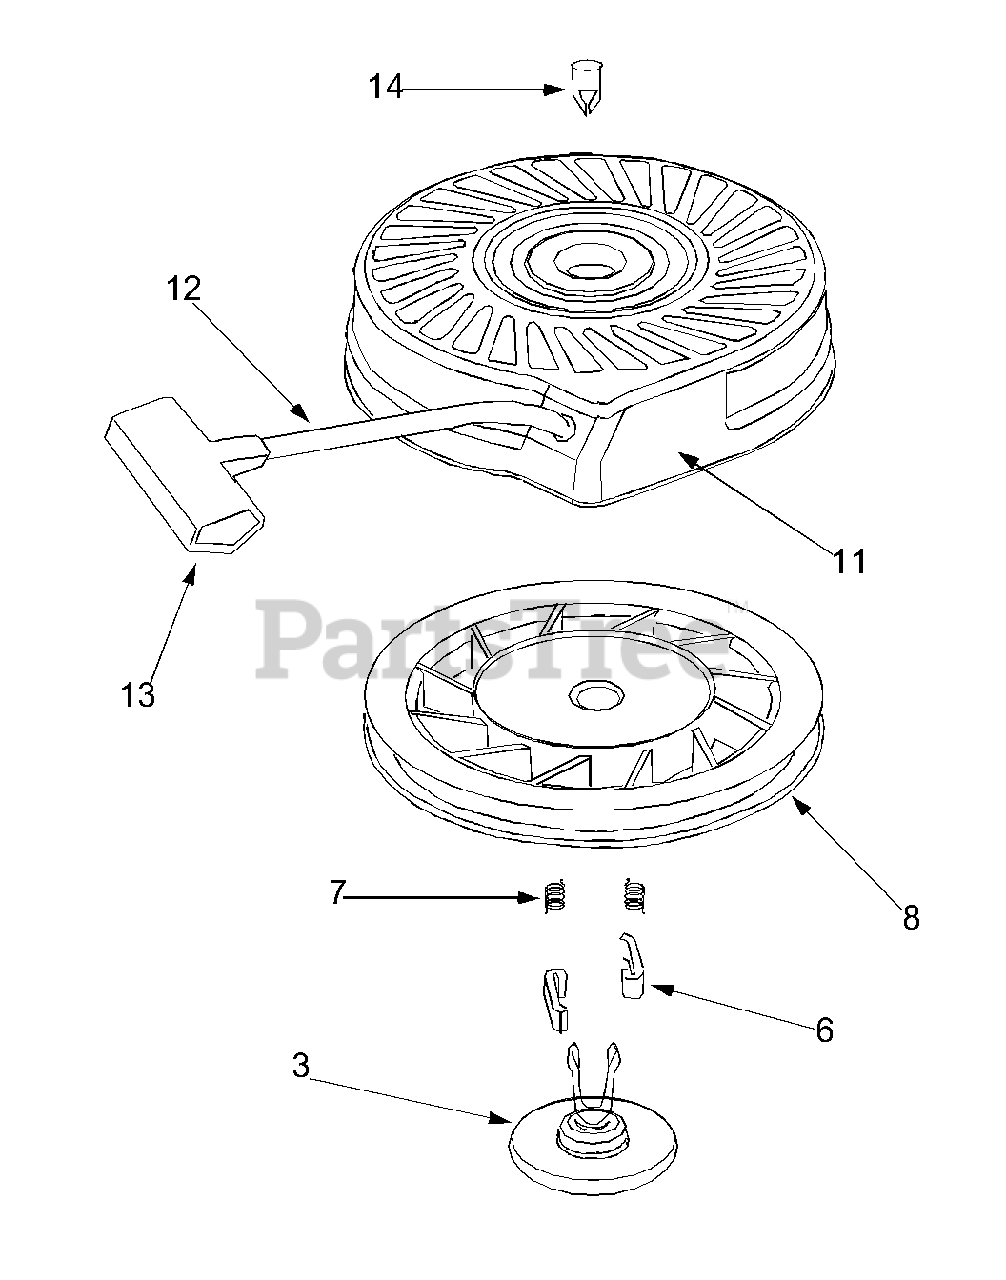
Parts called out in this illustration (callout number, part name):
3	Retainer
6	Starter Dog
7	Dog Spring
8	Pulley & Rewind Spring Ass'y
11	Starter Housing Assembly
12	Starter Rope
13	Starter Handle
14	Spring Clip
